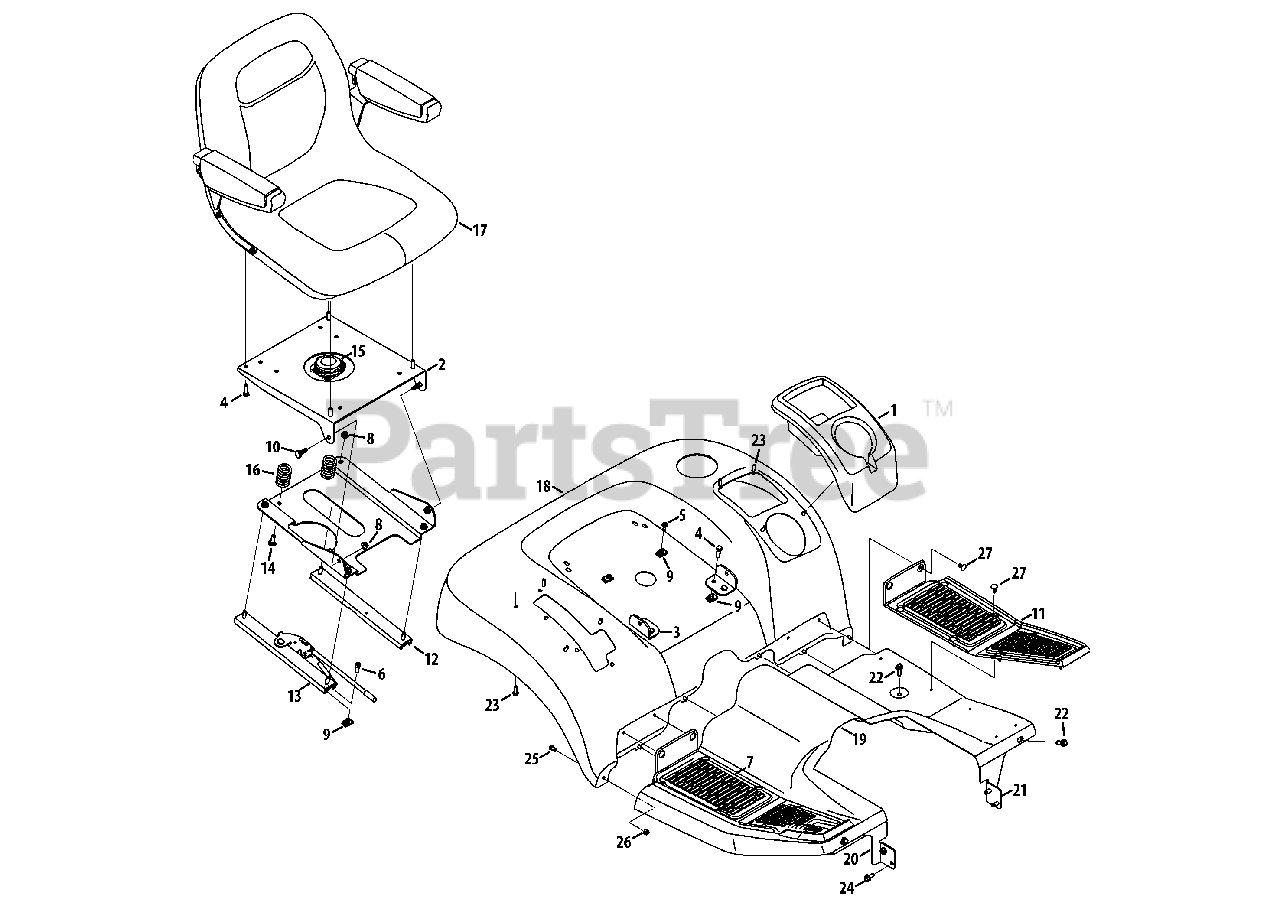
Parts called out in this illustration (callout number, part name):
1	LH Cup/Compartment Cover
2	Seat Mount Plate
3	Suspension Seat Front Pivot Bracket
4	Hex Screw, 5/16-18 x 1.00
5	Hex Flange Screw, 5/16-18
6	Socket Screw, 5/16-18 x .750
7	RH Floor Pad
8	Flange Lock Nut, 5/16-18
9	U-Nut, 5/16-18
10	Shoulder Screw, 5/16-18 x .437 x .268
11	LH Floor Pad
12	Seat Track w/o Latch
13	Seat Track w/ Latch
14	Carriage Screw, 5/16-18 x 1.00
15	Seat Switch, 1/4
16	Compression Spring
18	Fender
19	Running Board
20	RH Running Board Bracket
21	LH Running Board Bracket
22	Hex Washer Screw, 5/16-18 x 1.000
23	Hex Washer Screw, 1/4-15 x .750
24	Hex Washer Screw, 5/16-18 x .750
25	Hex Screw, 1/4-20 x .50
26	Hex Lock Nut, 1/4-20
27	Ratchet Clip, .250
